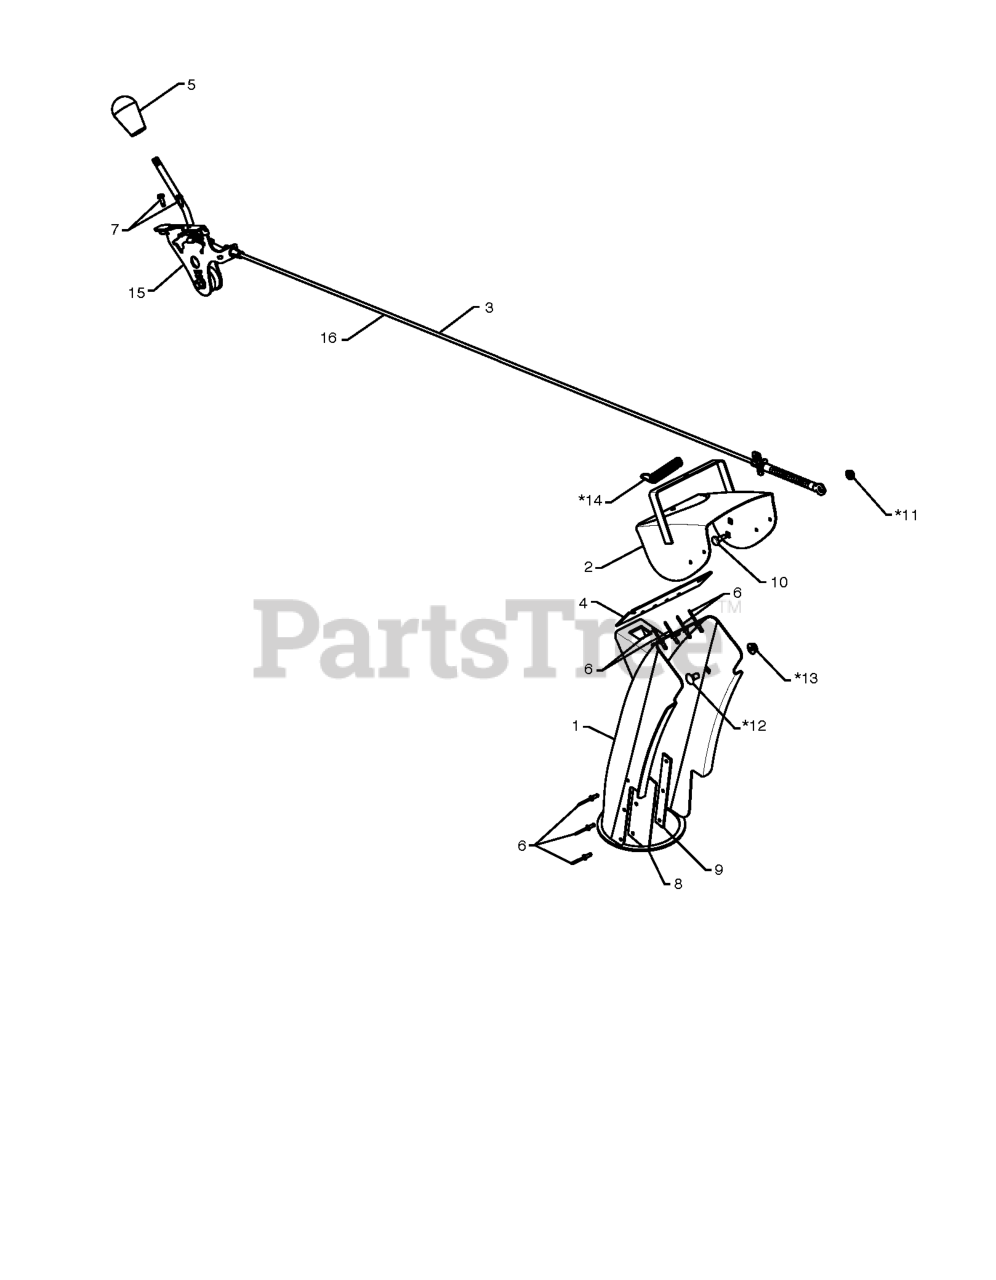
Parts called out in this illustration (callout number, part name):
1	CHUTE.WELDMENT
2	DEFLECTOR.WELDMENT.PNT.ORANGE
3	CONTROL.ASM.DEFLECTOR
4	SEAL.DEFLECTOR
5	KNOB LEVER, BLACK
6	RIVET BLIND
7	SCREW #10-24 X 5/8
8	SHIELD.SNOW.CHUTE
9	STRAP.SHEILD.RETAINER
10	BOLT, SHOULDER
11	NUT.HEX.FLANGE.1/4
12	BOLT
13	NUT.LOCK.5/16-18
14	SPRING.DEFLECTOR.REM.CHUTE
15	RP CNTRL.HEAD.ASSEM.DEFLECTOR
16	SERVICE.CHUTE.DEF.CBL.GRY
